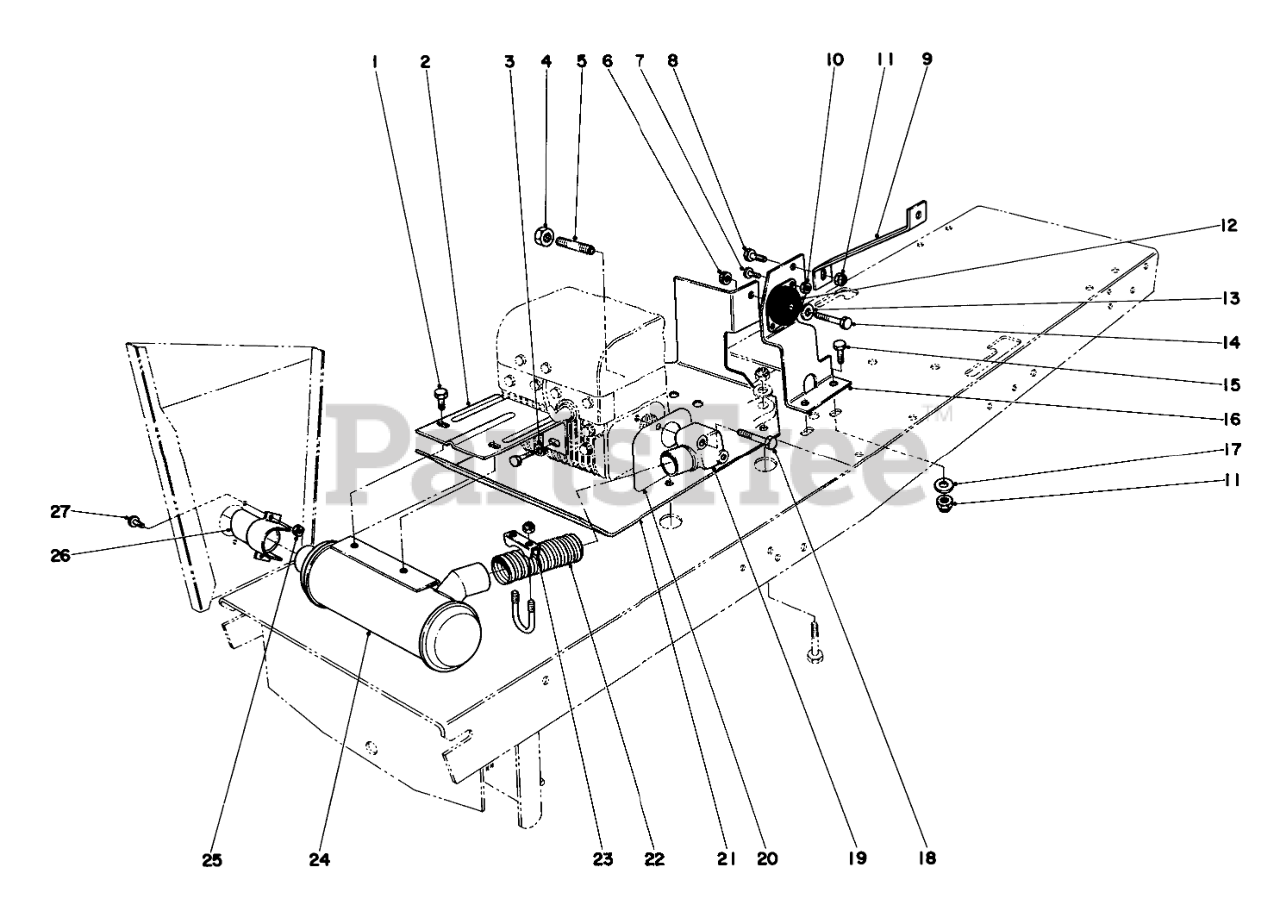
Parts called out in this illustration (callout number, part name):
1	SCREW-HH
2	Hanger Muffler
3	WASHER-LOCK
4	Cap-Pipe
5	NIPPLE 3/8NPTX 1.50
6	NUT-LOCK, SIDE
7	SCREW-PTH
8	SCREW-HH
9	Brace
10	NUT-LOCK, SIDE
11	NUT-LOCK, CONE
12	Mount Rubber
13	WASHER-FLAT
14	SCREW-HH
15	SCREW-HH
16	Mount Rear
17	WASHER-FLAT
18	Capscrew
19	Elbow Exhaust
20	Heat Shield
21	Engine Mount
22	Exhaust Tubing
23	Muffler Clamp
24	Muffler
25	NUT-LOCK, SIDE
26	Exhaust Tip
27	SCREW-PPH
